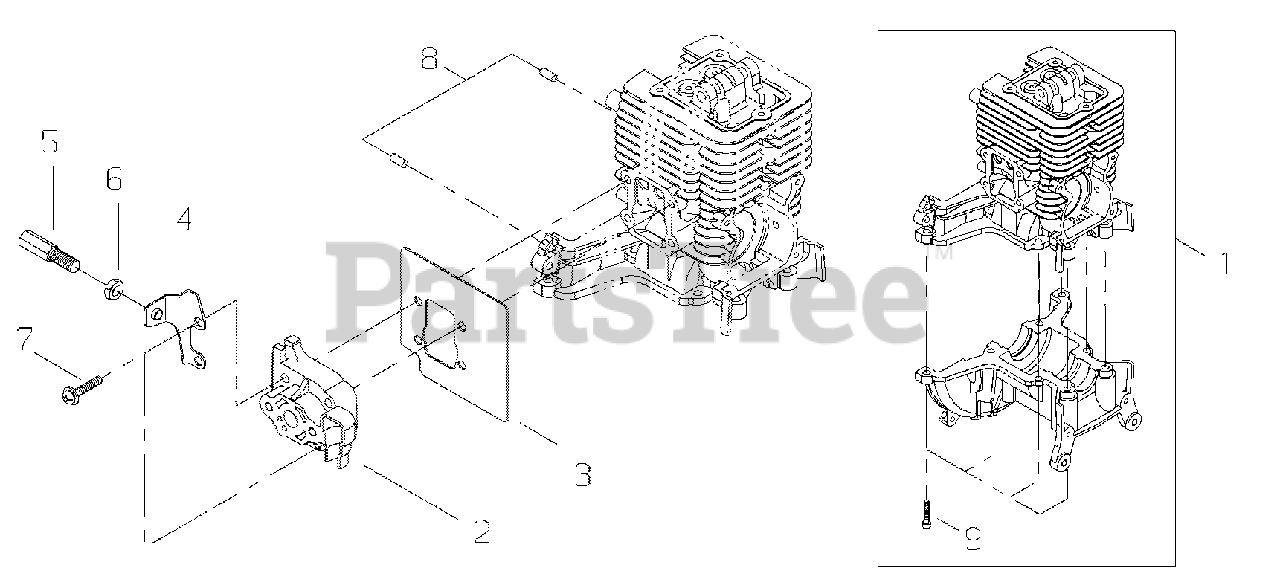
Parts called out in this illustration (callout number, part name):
1	CYLINDER & CRANKCASE ASSY
2	INSULATOR WITH REED VALVE
3	HEAT SHIELD, INTAKE
4	BRACKET, THROTTLE CABLE
5	ADJUSTER, THROTTLE CABLE
6	NUT, ADJUSTER LOCK M6
7	SCREW M5×25
8	PIN, LOCATING Ø4×8
9	BOLT 5×16
